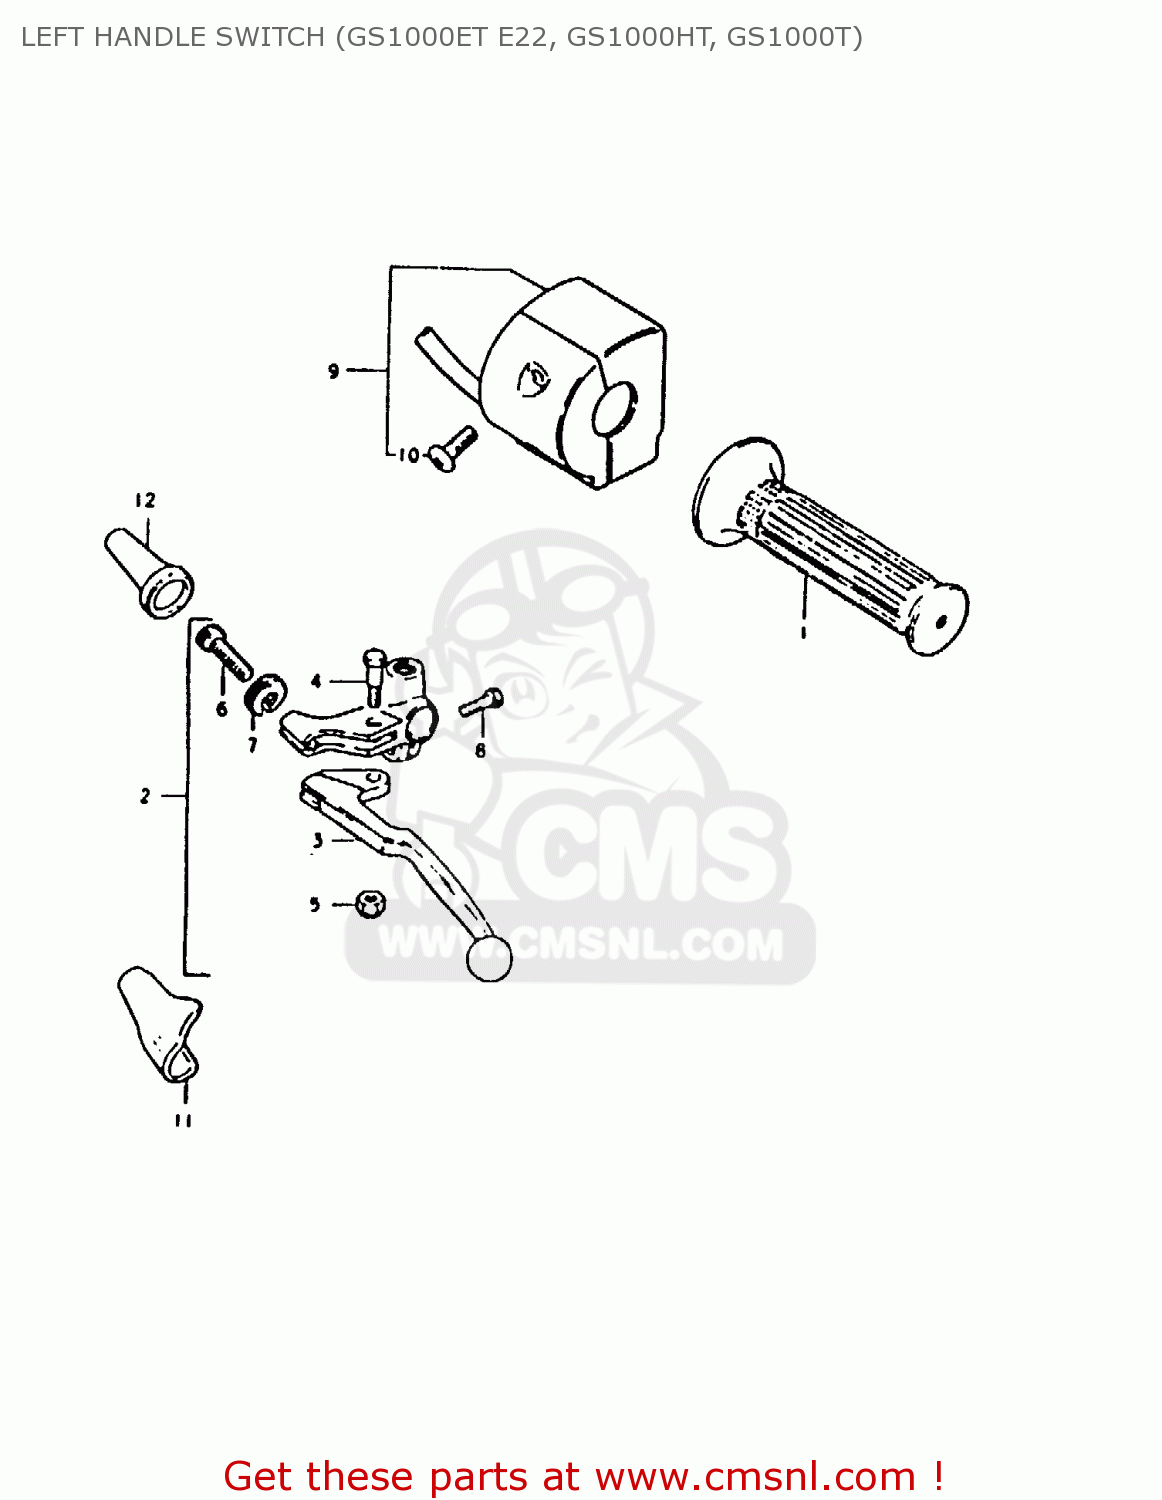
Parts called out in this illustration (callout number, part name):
1	GRIP,LEFT
2	LEVER ASSEMBLY
3	LEVER,CLUTCH
4	BOLT,LEVER
5	NUT 6MM
6	ADJUSTER,CABLE
7	NUT,CABLE ADJUSTER
8	BOLT
9	SWITCH ASSY, HANDLE LH
10	SCREW
11	COVER,CLUTCH LEVER
12	BOOT,CLUTCH CABLE
